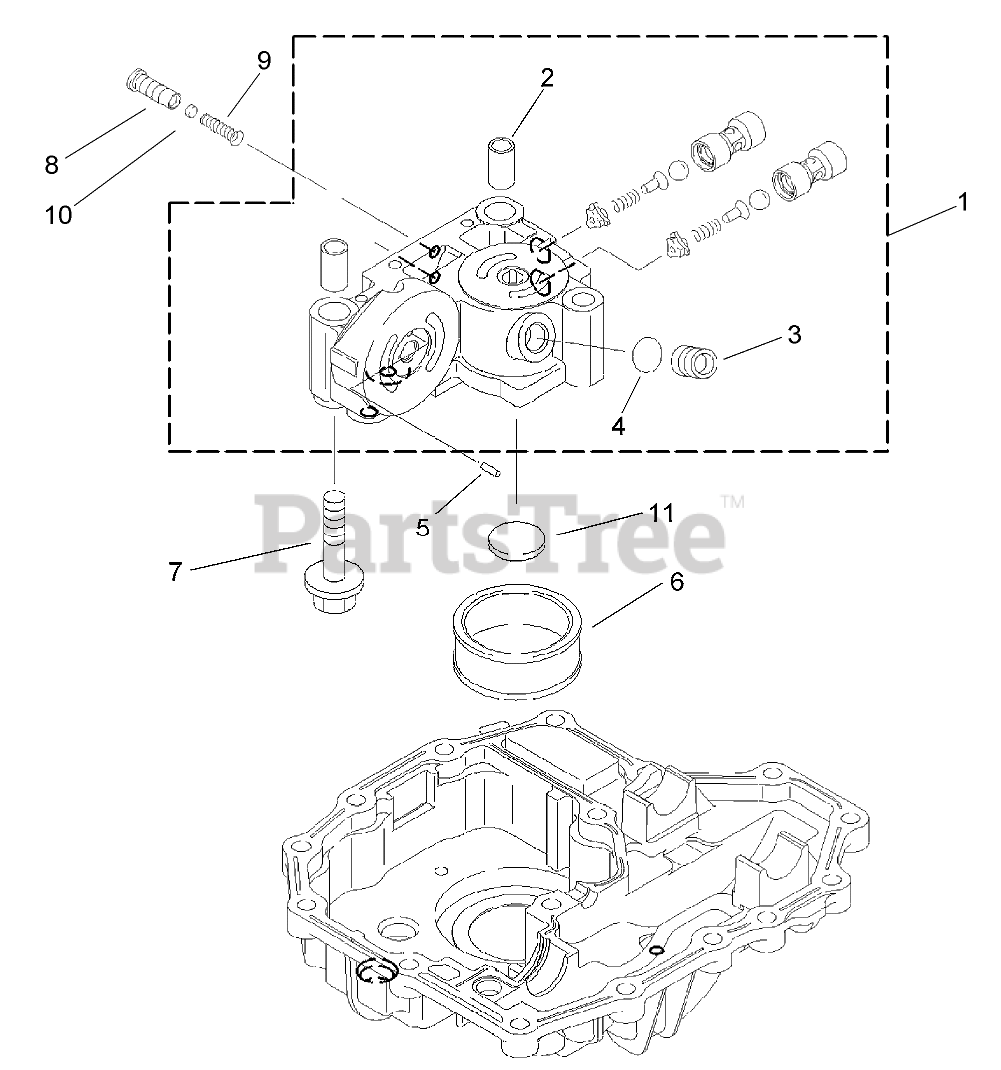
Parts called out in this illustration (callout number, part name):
1	Case-Center
2	Pin-Knock
4	PACKING
6	FILTER
9	Spring
10	Filter
11	Magnet
